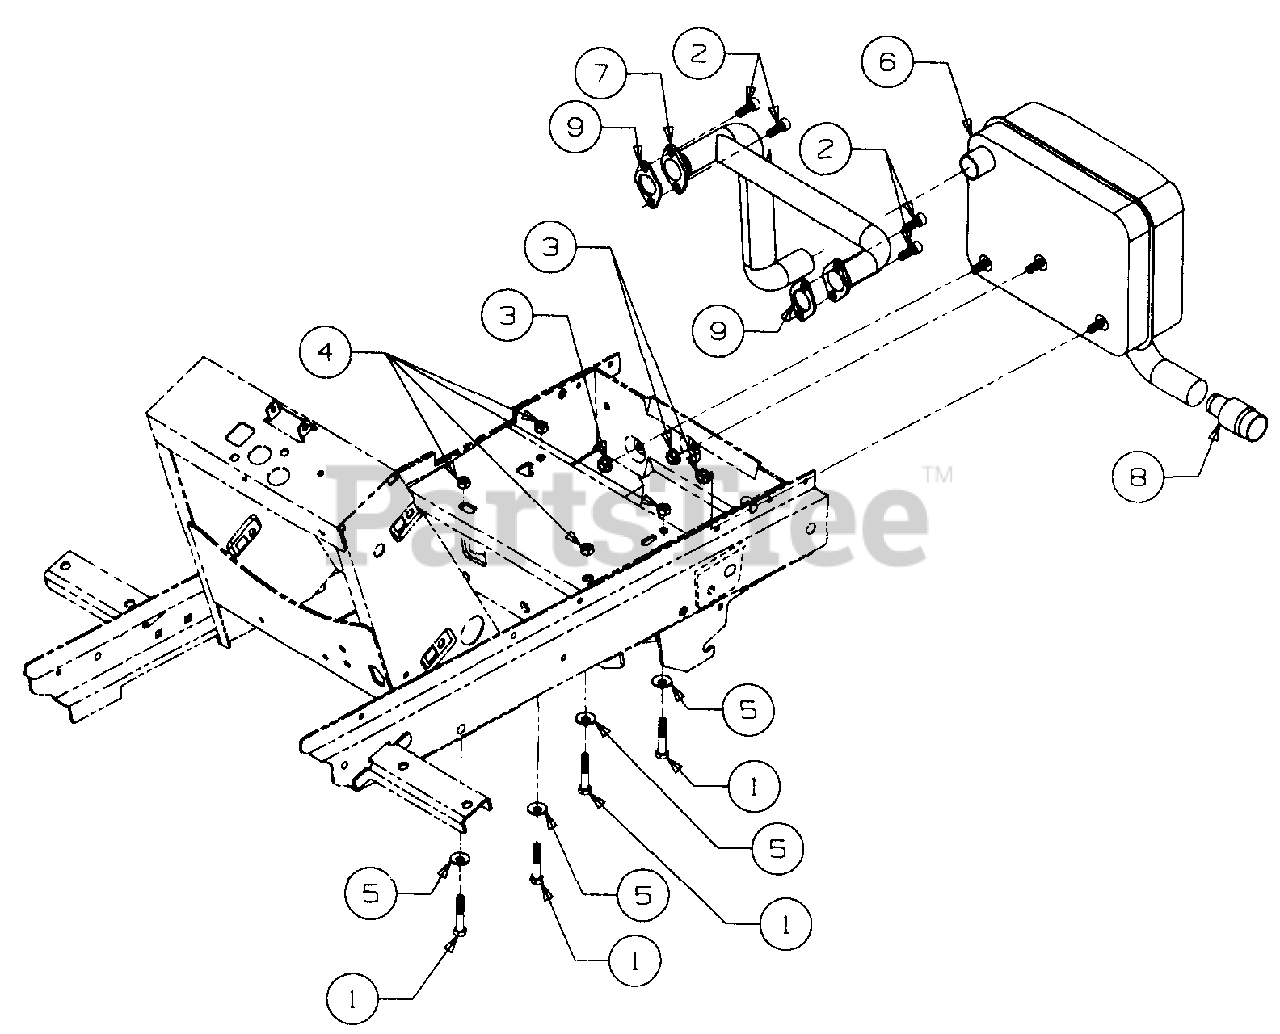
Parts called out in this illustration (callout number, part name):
1	Bolt, Engine Mtg, 5/16-18 x 1.75 Lg GR5
2	Screw, Socket Hd Cap, M8-1.25 x 20 mm Lg
3	Nut, Hex Flange Top Lock, 5/16-18
4	Nut, Hex, 5/16-18 GR5
5	Washer, Bell, .345 x .88 x .060 Thk
6	Muffler Assembly
7	Tube, Exhaust
8	Arrestor, Spark
9	Gasket, Exhaust
